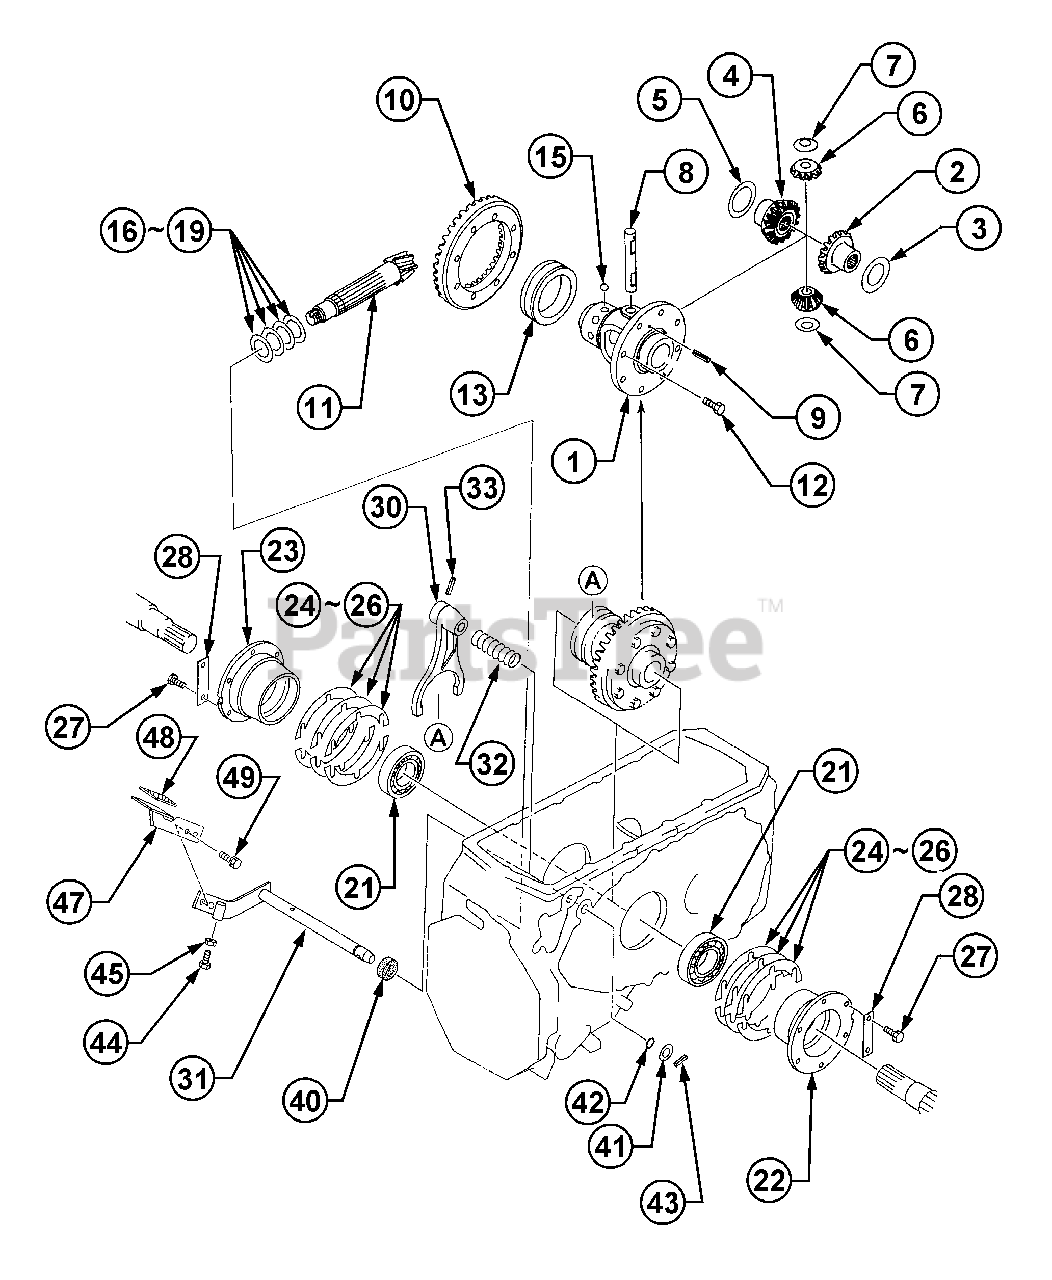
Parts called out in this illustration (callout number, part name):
2	Gear, Diff Side
3	Washer, Thrust
4	Gear, Diff Side
5	Washer, Thrust
7	Washer, Thrust
10	Gear, Ring
11	Pinion
13	Hub, Diff Lock
31	Shaft, Diff Lock
49	Bolt, w/Washer
